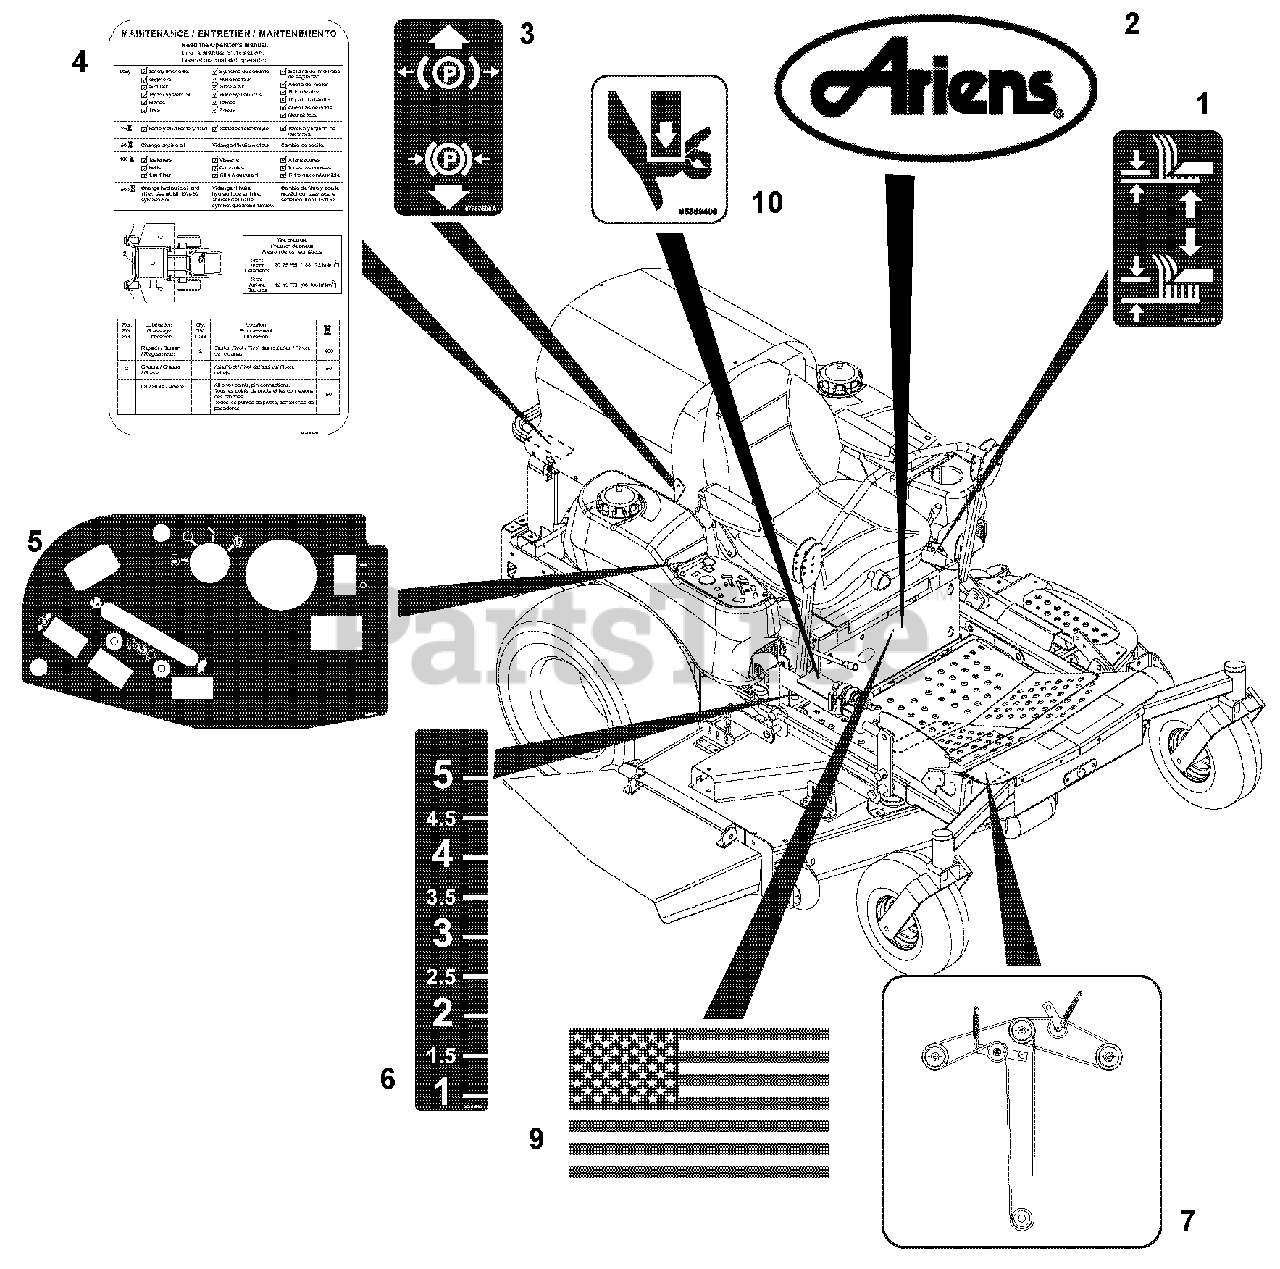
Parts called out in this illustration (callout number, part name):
1	Decal, Lift Lever
2	Decal, Ariens
3	Decal, Parking Brake Lever
4	Decal, Service Instructions
5	Decal, Control Panel
6	Decal, Height of Cut
7	Decal, Belt Diagram
8	Decal, PM-260Z
9	Decal, American Flag
10	Decal, Pinch Point
